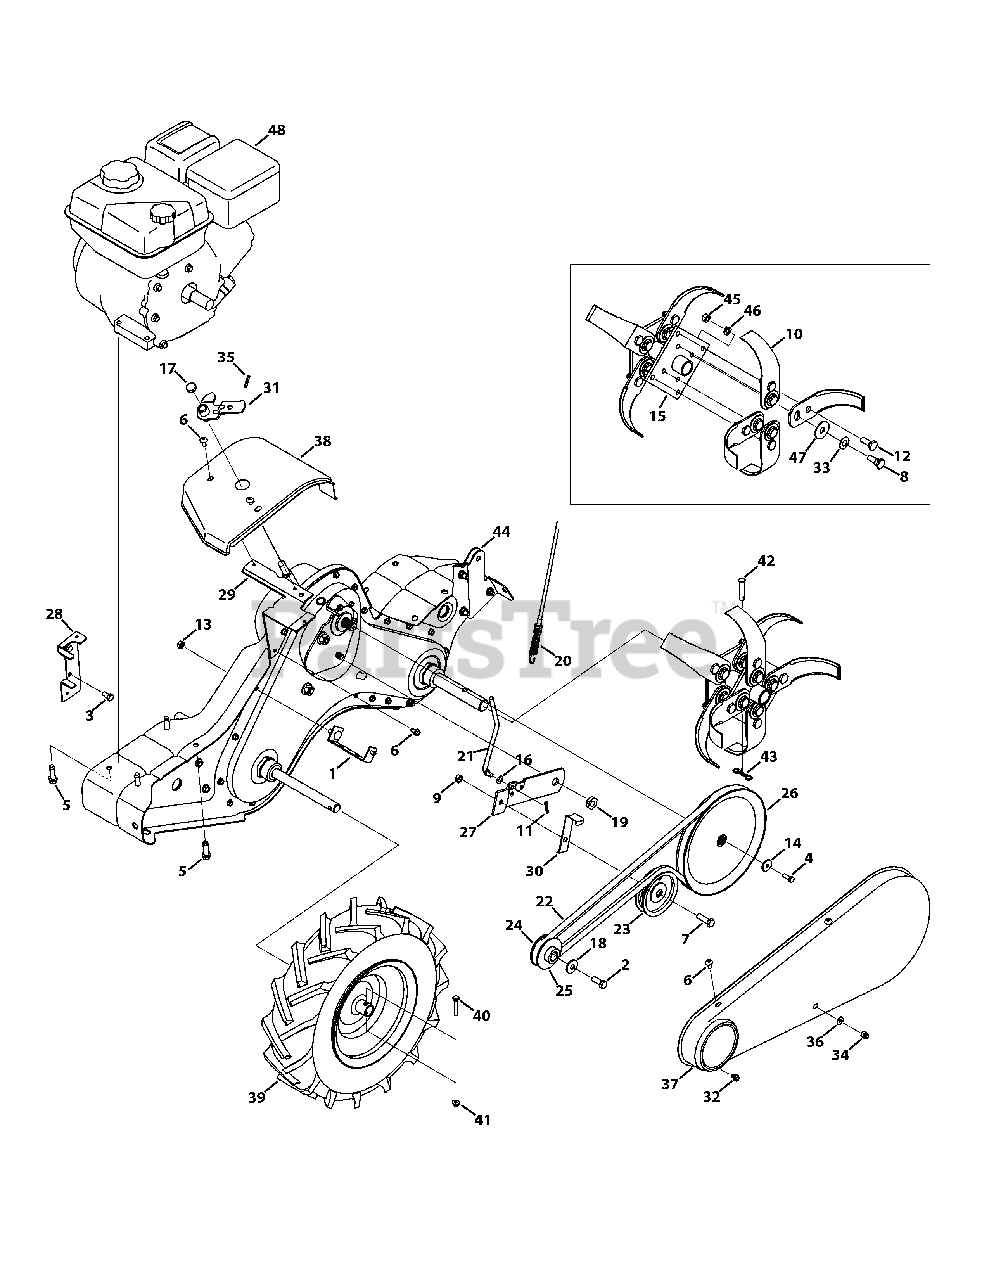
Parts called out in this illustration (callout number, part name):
1	Belt Cover Bracket Assembly
2	Hex Screw, 3/8-24 x 1.00
3	Hex Lock Screw, 5/16-24 x .625
4	Hex Lock Screw, 1/4-28 x .625
5	Screw, 3/8-16 x 1.250
6	Hex Washer Screw, 1/4-20 x 0.625
7	Hex Screw, 3/8-16 x 1.25
8	Shoulder Screw, 3/8-24 x 1/2 x .325
9	Jam Lock Nut, 3/8-16
10	Articulating Tine
11	Cotter Pin, .072 x 1.13
12	Shoulder Screw, 3/8-24 x 1/2 x .180
13	Flange Lock Nut, 5/16-18
14	Flat Washer, .265 x .938 x .120
15	Tine Adaptor Assembly
15	Tine Assembly
16	Washer, Spring, .317 x .625 x .020
18	Bell Washer, .396 x 1.140 x .095
19	Shoulder Nut, 7/16-20
20	Clutch Cable
21	Idler Pulley Rod
23	Flat Idler Pulley, 3.75
24	Engine Pulley, Inner Half
25	Engine Pulley, Outer Half
26	Input Pulley, 4 x 8.594
27	Idler Pulley Bracket
28	Belt Keeper Bracket
29	Shift Cover Bracket
30	Idler Belt Keeper
31	Shift Crank Assembly
32	Screw, 1/4-20:0.375
33	Bell Washer, .525 x 1.00 x .050
34	Lock Nut, 1/4-28
35	Spiral Pin, 3/16 x 1.00
36	Flat Washer, .271 x .630 x .065
37	Belt Cover
38	Shift Cover
39	Wheel, 16 x 4.6 x 8
40	Hex Screw, 1/4-20 x 1.50
41	Flange Lock Nut, 1/4-20
42	Clevis Pin, .375 x 1.75
43	Cotter Pin
44	Complete Gear Case Assembly
45	Hex Lock Nut, 3/8-24
46	Lock Washer, 3/8
47	Flat Washer, .51 x 1.5 x 0.07
48	Replacement Engine
